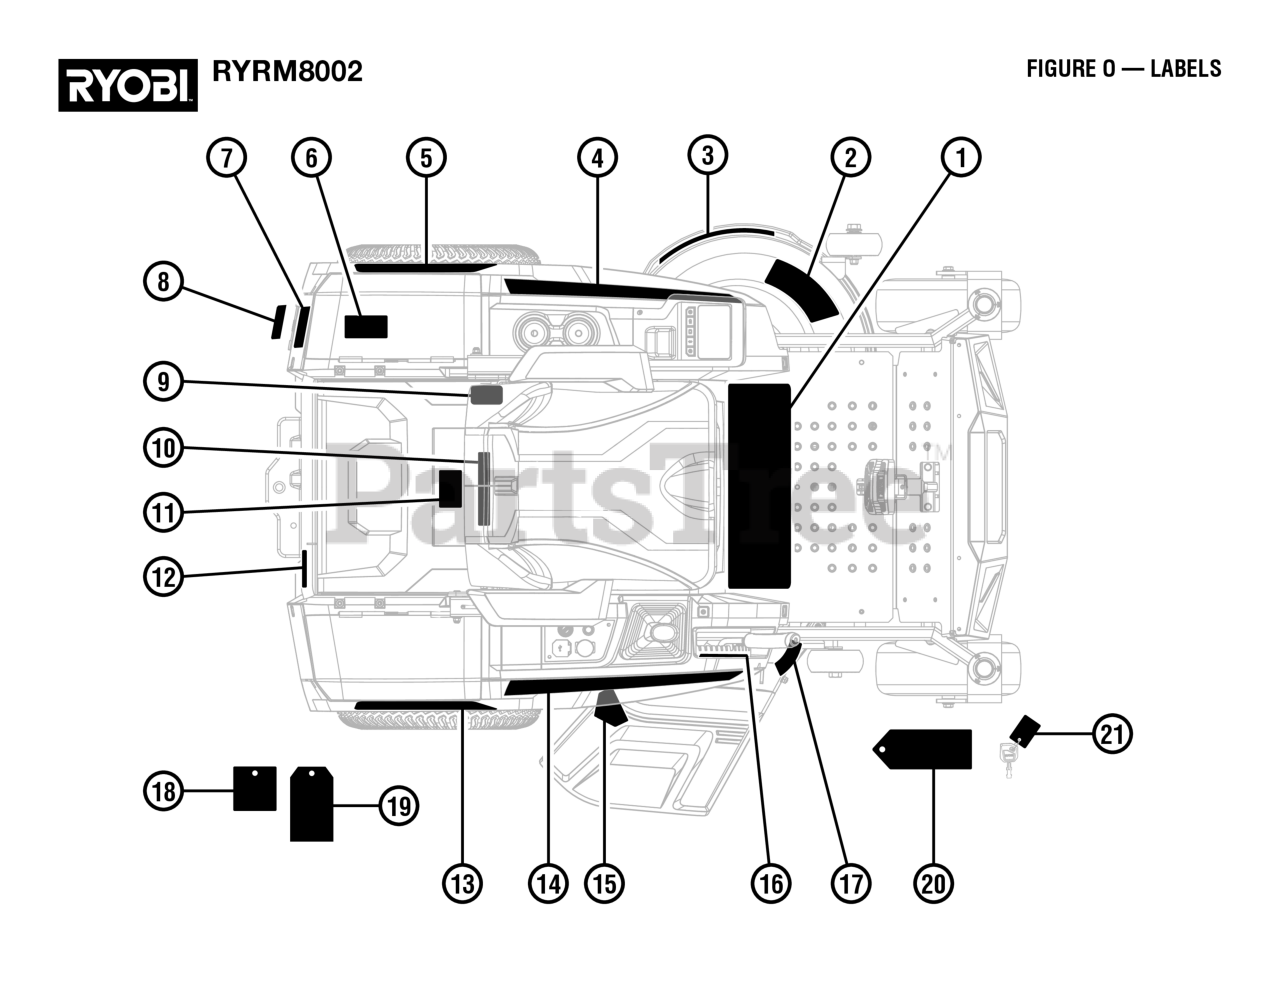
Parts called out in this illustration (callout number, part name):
1	Danger/Warning/Joystick Control/Brake Label (Eng)
1	Danger/Warning/Joystick Control/Brake Label (Sp)
2	Deck Danger Label, English
2	Deck Danger Label, Spanish
3	Cutting Width Deck Label
4	80V HP Brushless Hero Label
5	Sub Brand Logo Hero Label
6	40V Battery Connection Instrucion Card
8	Charging Port Label (Eng)
8	Charging Port Label (Sp)
9	Data Label
10	FCC Label
11	80V Battery Connection Instrucion Card
12	Bagging Label (Eng)
12	Bagging Label (Sp)
13	Sub Brand Logo Non-Hero Label
14	80V HP Brushless Non-Hero Label
15	No Hands CPSC Danger Label, English
15	No Hands CPSC Danger Label, Spanish
16	Deck Height Adjustment Label
17	Discharge Chute Icons
18	Prop 65 Hangtag
19	Seat Assembly Tag
20	Joystick Hangtag
21	Key Chain Tag (Eng)
21	Key Chain Tag (Sp)
